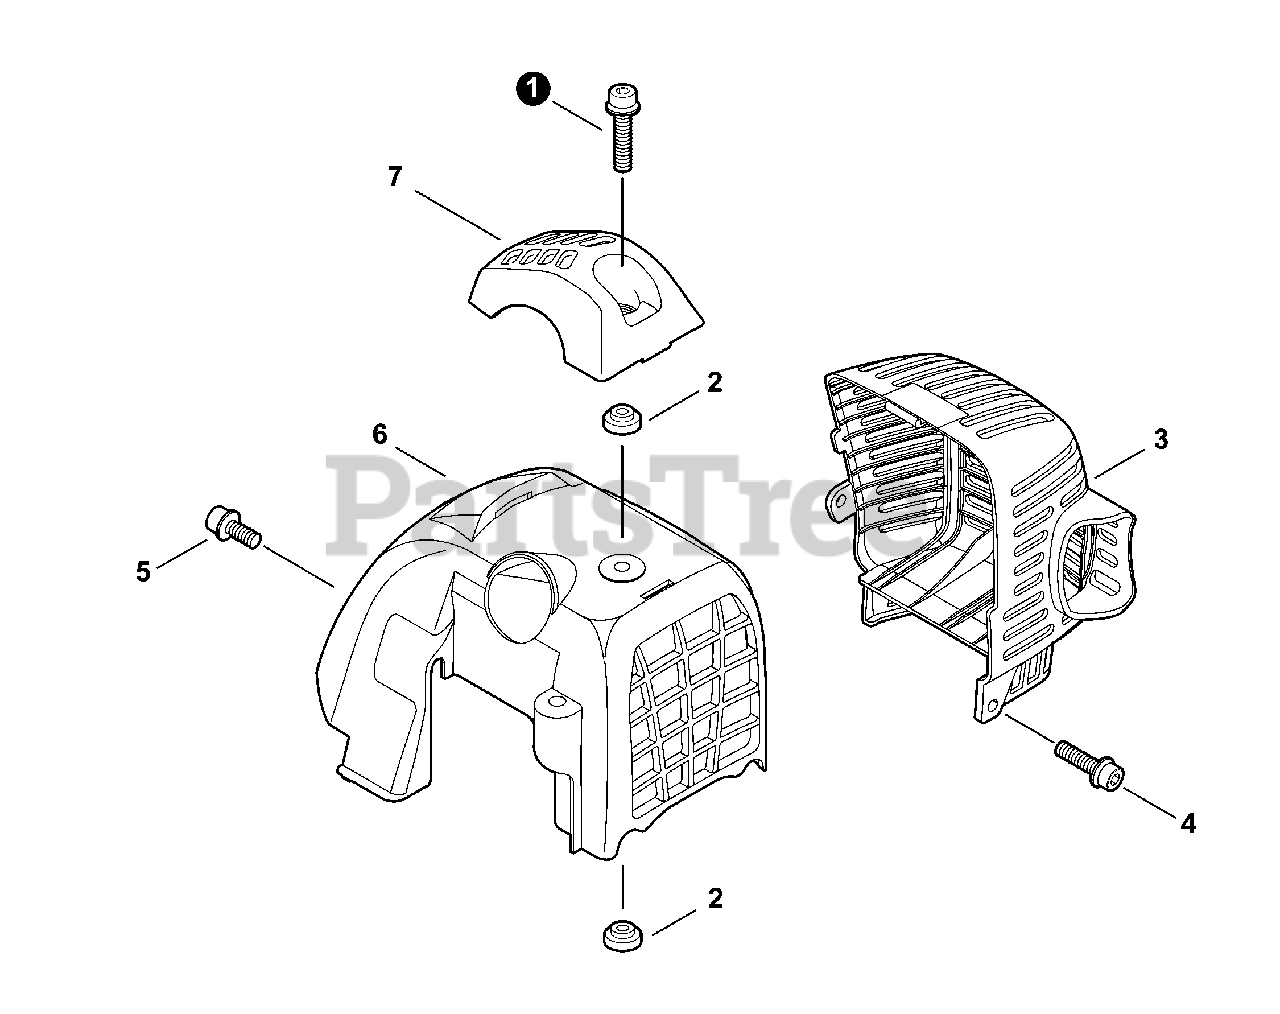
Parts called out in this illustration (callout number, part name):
1	SCREW - 5×20
2	COLLAR - 5
3	COVER, EXHAUST
4	SCREW - 5×16
5	SCREW - 5×10
6	COVER, ENGINE
7	GUARD,TOP
